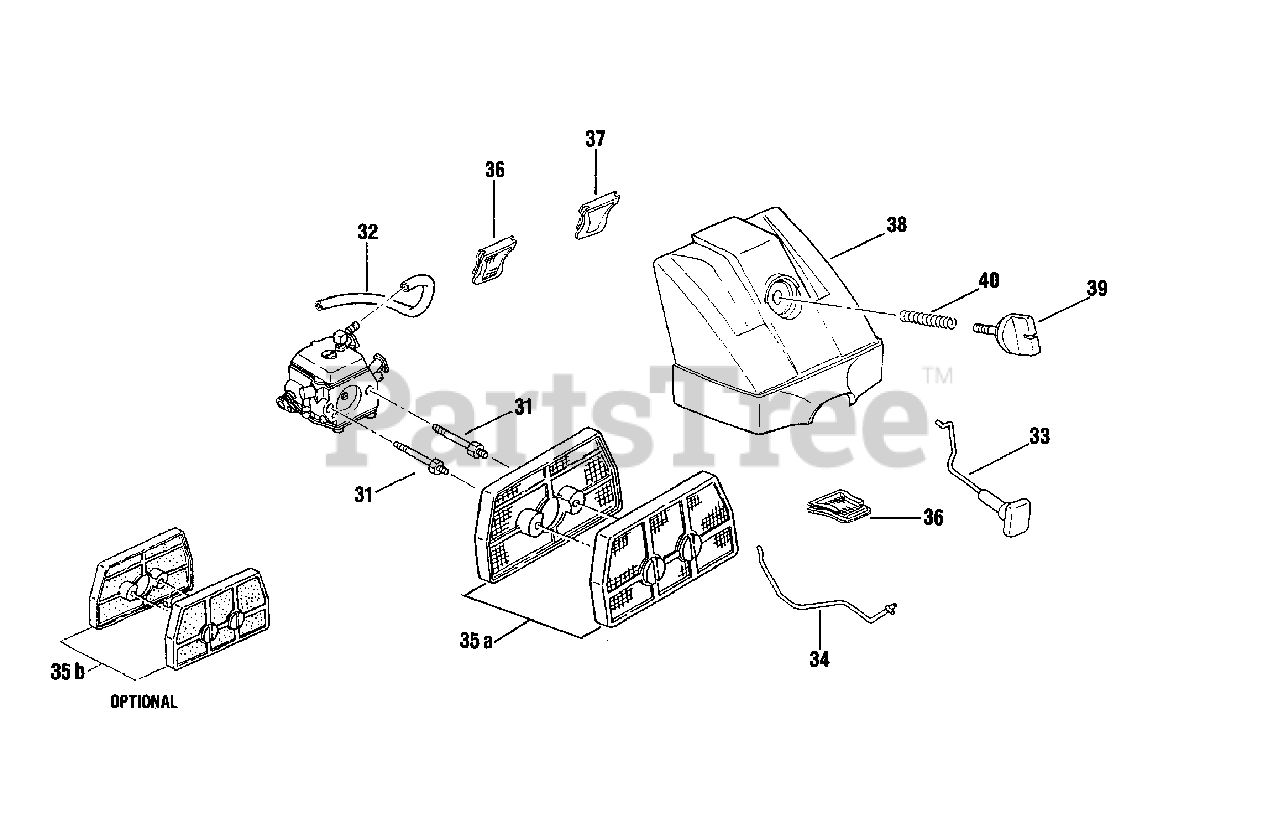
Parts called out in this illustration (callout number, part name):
31	BOLT
32	PIPE - IMPULSE
33	ROD, CHOKE
34	ROD, THROTTLE
35A	AIR FILTER ASSY - STAINLESS
35B	FILTER, AIR - FLOCKED
36	PRE-FILTER
37	PLUG
38	FILTER COVER
39	THUMBSCREW
40	SPRING
